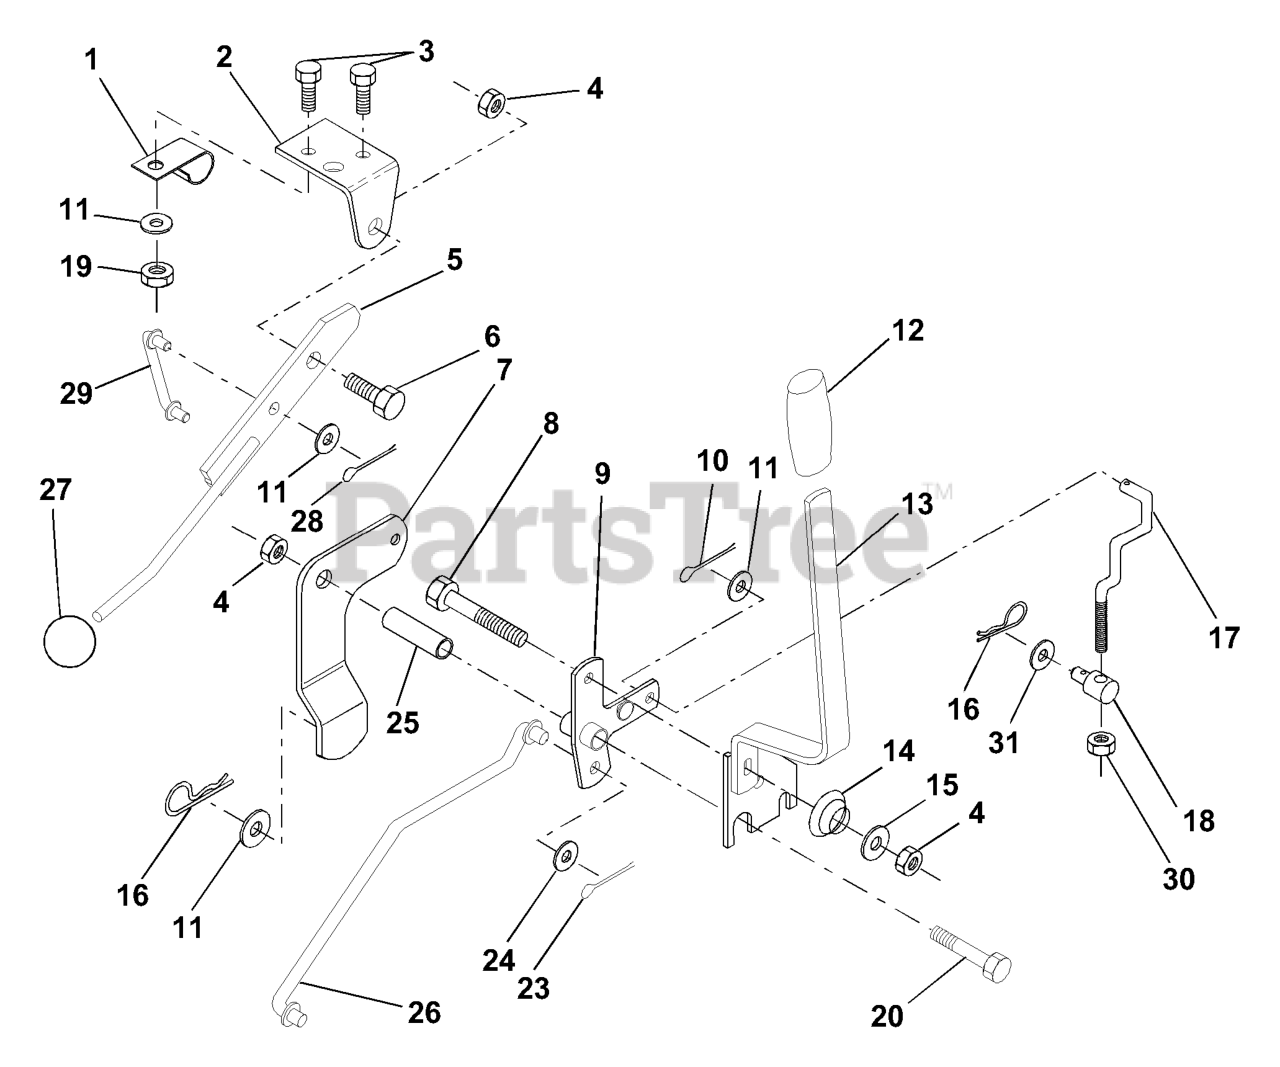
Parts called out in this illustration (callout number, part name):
1	CLIP,INSULATOR
2	BRKT CLUTCH
3	BOLT
5	CLUTCH LEVER ASSY
6	BOLT, SHOULDER LT
7	ASSEMBLY MOWER CLUTCH ARM
9	BELLCRANK,LIFT
10	COTTER PIN
11	WASHER
12	HANDLE GRIP
13	LIFT HANDLE ASSY
14	SPRING COMPRESSIO
15	WASHER T
16	SPRING TI
17	LINK LIFT FRT
18	TRUNNION.ADJUSTABLE.3/8-16
19	NUT.CROWNLOCK.1/4
23	PIN COTTER
24	WASHER GT
25	TUBE SPACER
27	KNOB T (3/8 HOLE)
28	COTTER PIN
29	LINK MOWER CLUTCH
30	NUT
31	WASHER
